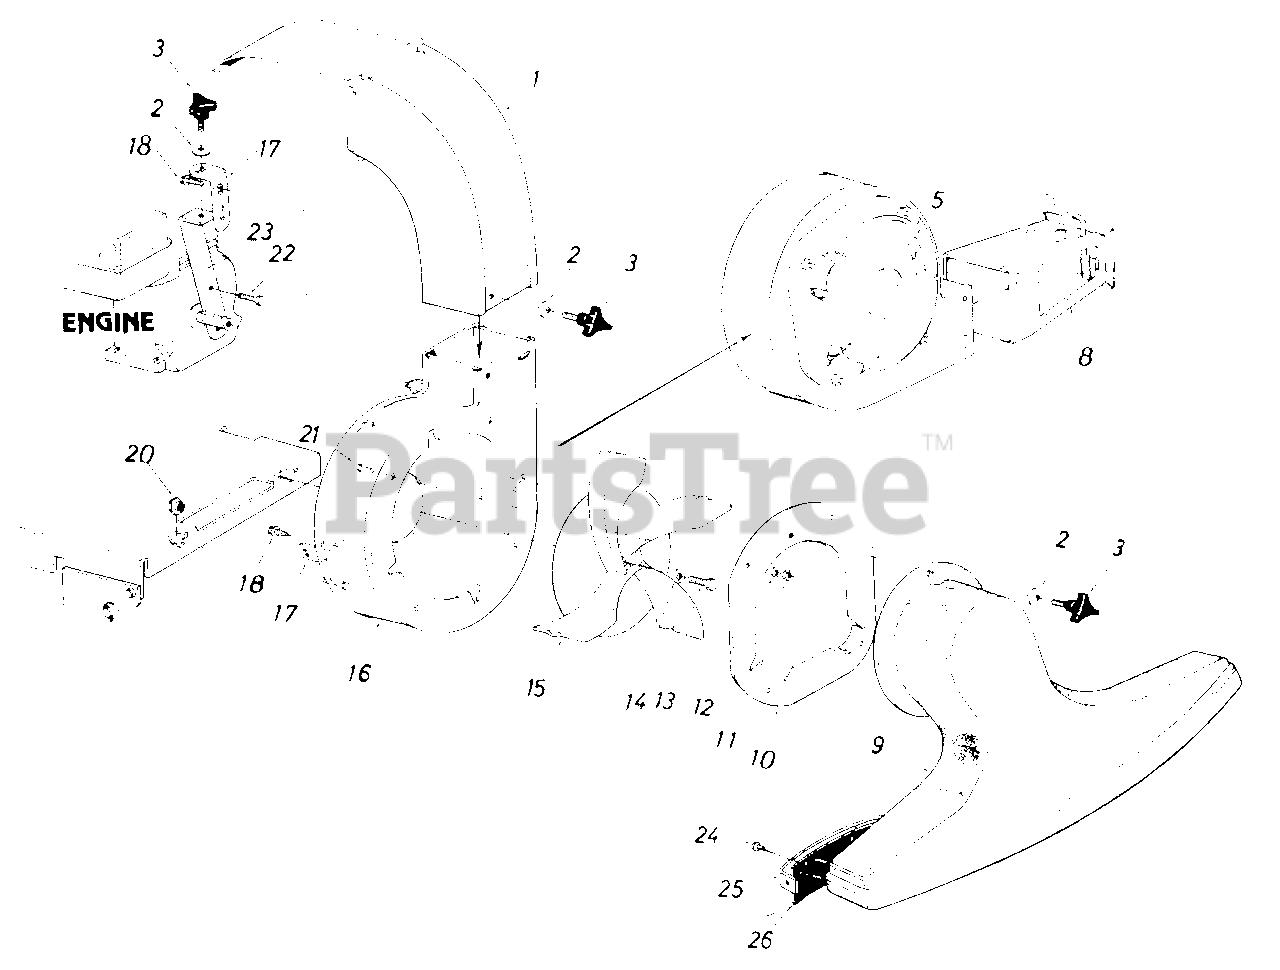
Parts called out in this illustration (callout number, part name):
3	KNOB-THREE ARM
5	GUARD-BLOWER
10	PLATE ASSY-NOZZLE
11	NUT-HEX 5/16-18
12	WASHER-LOCK-5/16
13	SCREW 3/8-24X1.25 GR5
14	WASHER-HDL 3/8
15	PLATE ASSY-VANE
16	HOUSING ASSY-BLOWER
20	NUT-HEX SHLD
21	BOLT-CARRIAGE 5/16-18 X .62
22	SCREW-CAP LOCK 5/16-24 X .75
